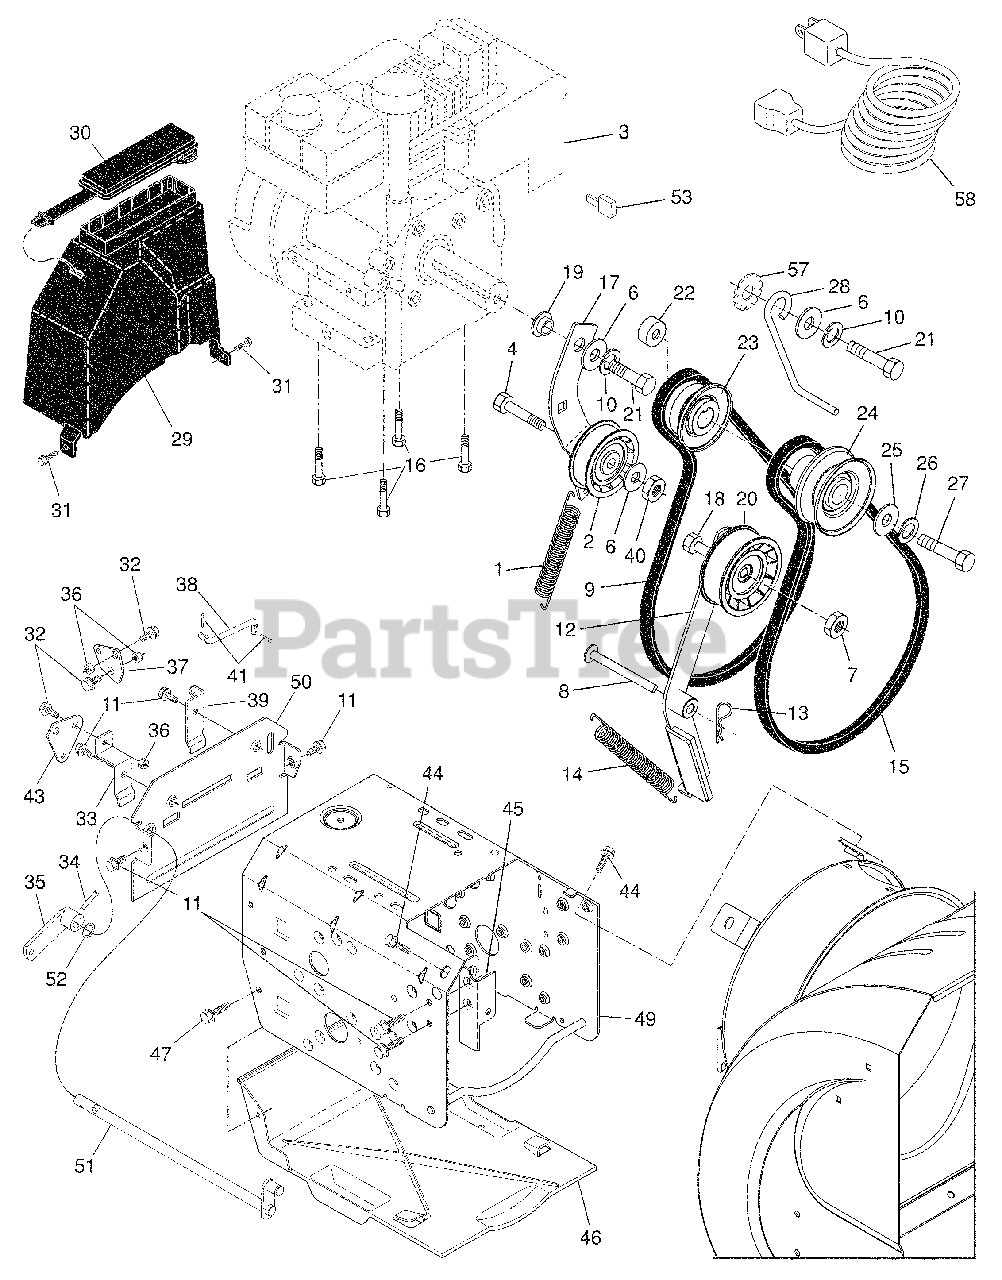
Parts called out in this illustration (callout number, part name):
1	Spring, Traction Idler
2	Pulley, Idler (2-1/4)
4	Screw, Hex Head 5/16-18 x 1-1/4
6	Washer, Flat
7	Nut, Jam, Lock 5/16-18
8	Pin, Idler Pivot
9	V-Belt, Traction Drive
10	Washer, Lock 5/16
11	Screw, Hex Head 5/16-18 x 1/2
12	Impeller Arm / Pad Assembly
13	Retainer, Hairpin
14	Spring, Brake
15	V-Belt, Impeller Drive
16	Screw, Hex Head 3/8-16 x 1-1/4
17	Arm, Idler
18	Screw, Hex Head 5/16-18 x 1-1/2
19	Bushing, Idler Pivot
20	Pulley, Idler (2-3/4)
21	Screw, Hex Head 5/16-18 x 1
22	Spacer, Engine Pulley
23	Pulley, Engine, Traction Drive
24	Pulley, Engine, Impeller Drive
25	Washer, Flat 3/8
26	Washer, Lock, Helical 3/8
27	Screw, Hex Head 3/8-24 x 1-3/8
28	Guide, Belt
29	Belt Cover Assembly
30	Cover, Toolbox
31	Screw, Hex Head 1/4-20 x 1/2
32	Bolt, Shoulder 3/8-25
33	Bracket, Shifter
34	Clevis, Pin
35	Arm, Auger Control
36	Nut 1/4-20
37	Plate, Clutch
38	Link, Speed Control
39	Bracket, Clutch
40	Locknut, Hex
41	Hairpin, Cotter 3/32 x 1/2
43	Plate, Shifter
44	Screw, Hex Head
45	Pivot Bracket, Impeller Idler Arm
46	Pan, Frame Bottom
47	Screw, Hex Head 5/16-18 x 3/4
49	Frame Assembly
50	Plate, Rear
51	Shaft, Auger Control
52	Washer, Hardened
53	Key, Safety
57	Washer, Lock, External Tooth 5/16
58	Power Cord
